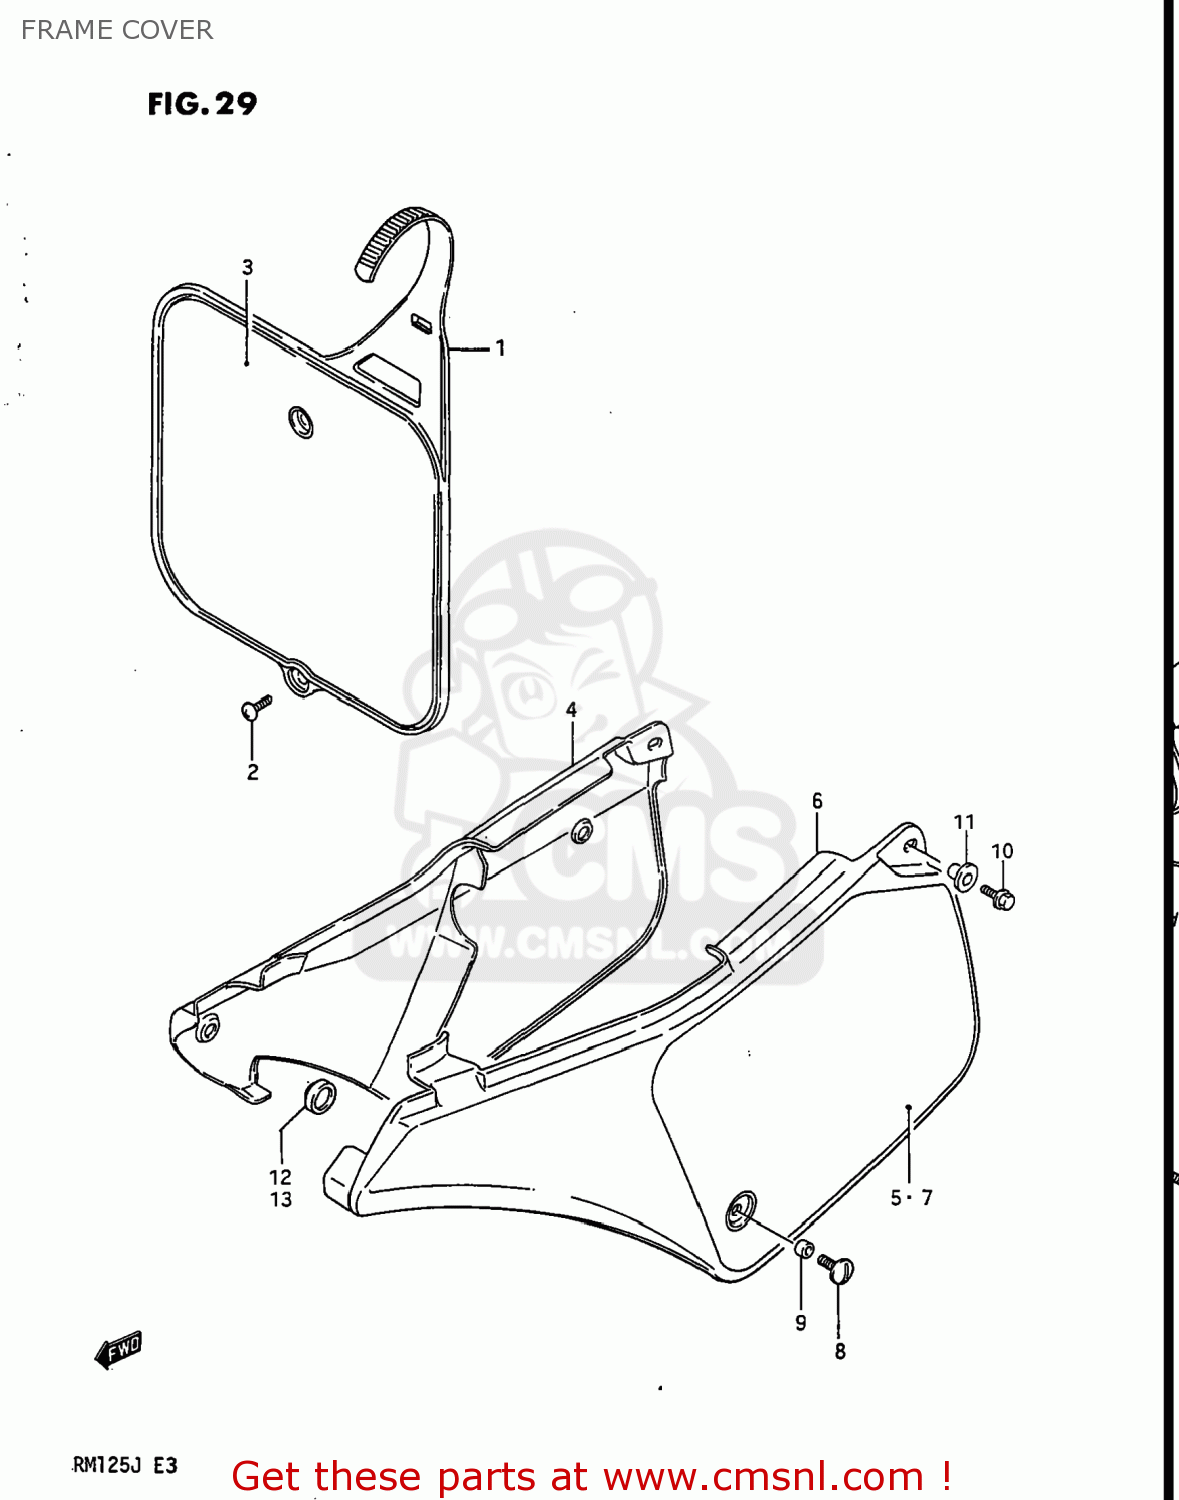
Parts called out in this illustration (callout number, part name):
1	PLATE,NUMBER,FRONT
2	SCREW
3	TAPE,FRONT NUMBER PLATE
4	COVER,FRAME,RIGHT
5	EMBLEM,FRAME COVER,NUMBER PLATE
6	COVER,FRAME,LEFT
7	EMBLEM,FRAME COVER,NUMBER PLATE
8	SCREW(6X14)
9	SPACER (6.1X8X3.5)
10	BOLT
11	WASHER
12	CUSHION
13	CUSHION
